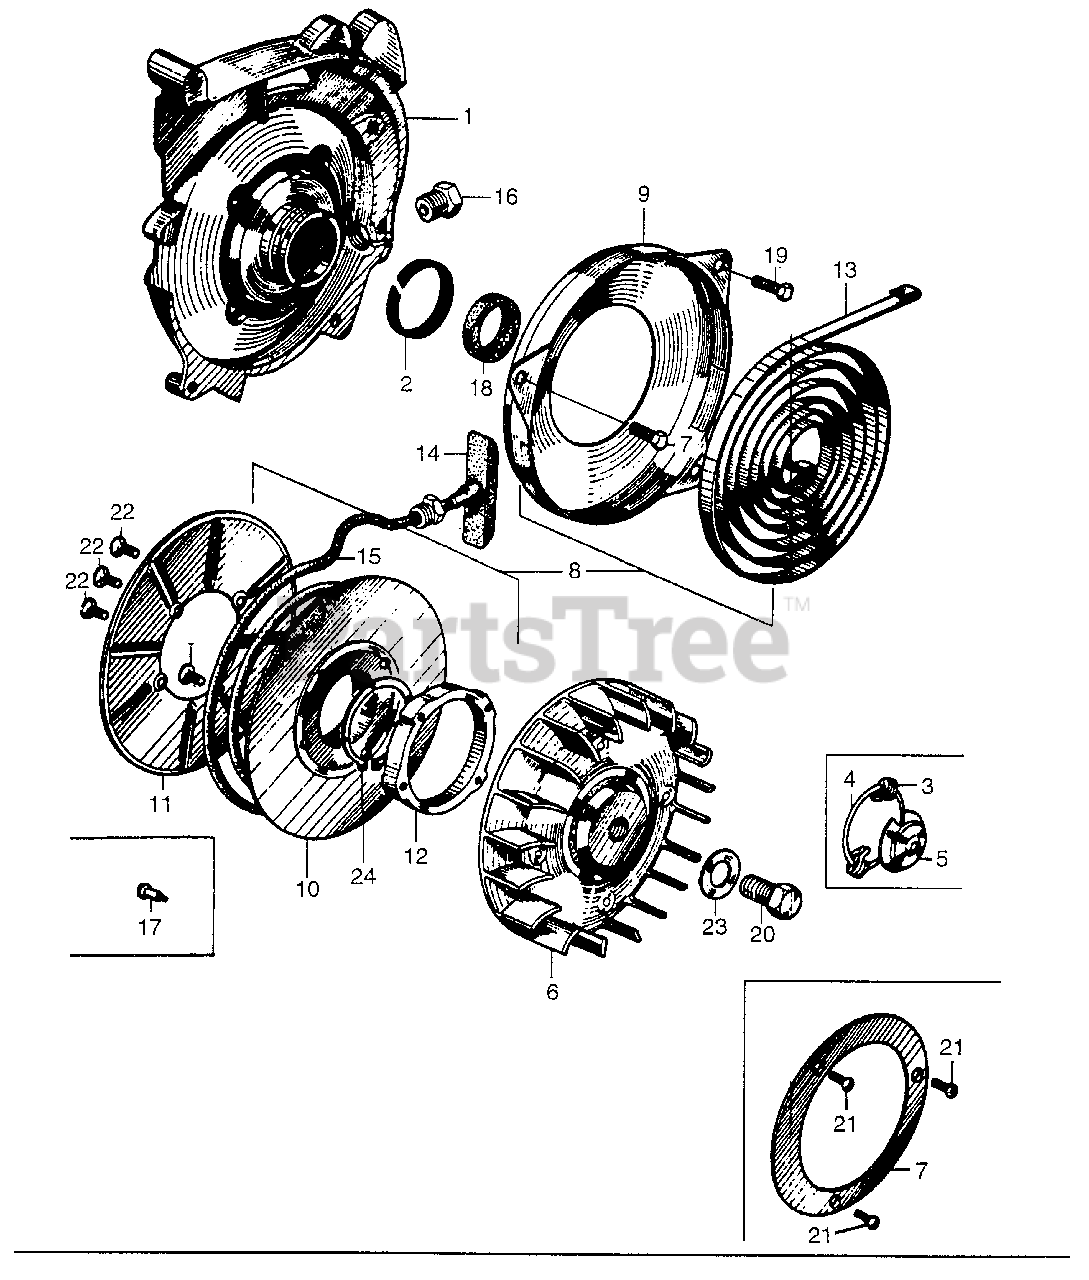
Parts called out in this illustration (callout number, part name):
1	CASE, STARTER
2	FELT (4.5MM)
6	FAN, COOLING
8	STARTER ASSY., RECOIL (NOT AVAILABLE)
9	CASE, SPRING (NOT AVAILABLE)
10	PULLEY, STARTER
11	PLATE, STARTER (NOT AVAILABLE)
12	RATCHET, STARTER (NOT AVAILABLE)
13	SPRING, STARTER RETURN
15	ROPE, STARTER (#5.5X79")
16	GUIDE, ROPE (NOT AVAILABLE)
18	OIL SEAL (15X24X5)
19	BOLT, HEX. (5X10)
20	BOLT, FLANGE (8X20)
22	SCREW, FLAT (5X14)
23	WASHER, ROTOR SETTING (NOT AVAILABLE)
24	CIRCLIP (OUTER) (30MM)
